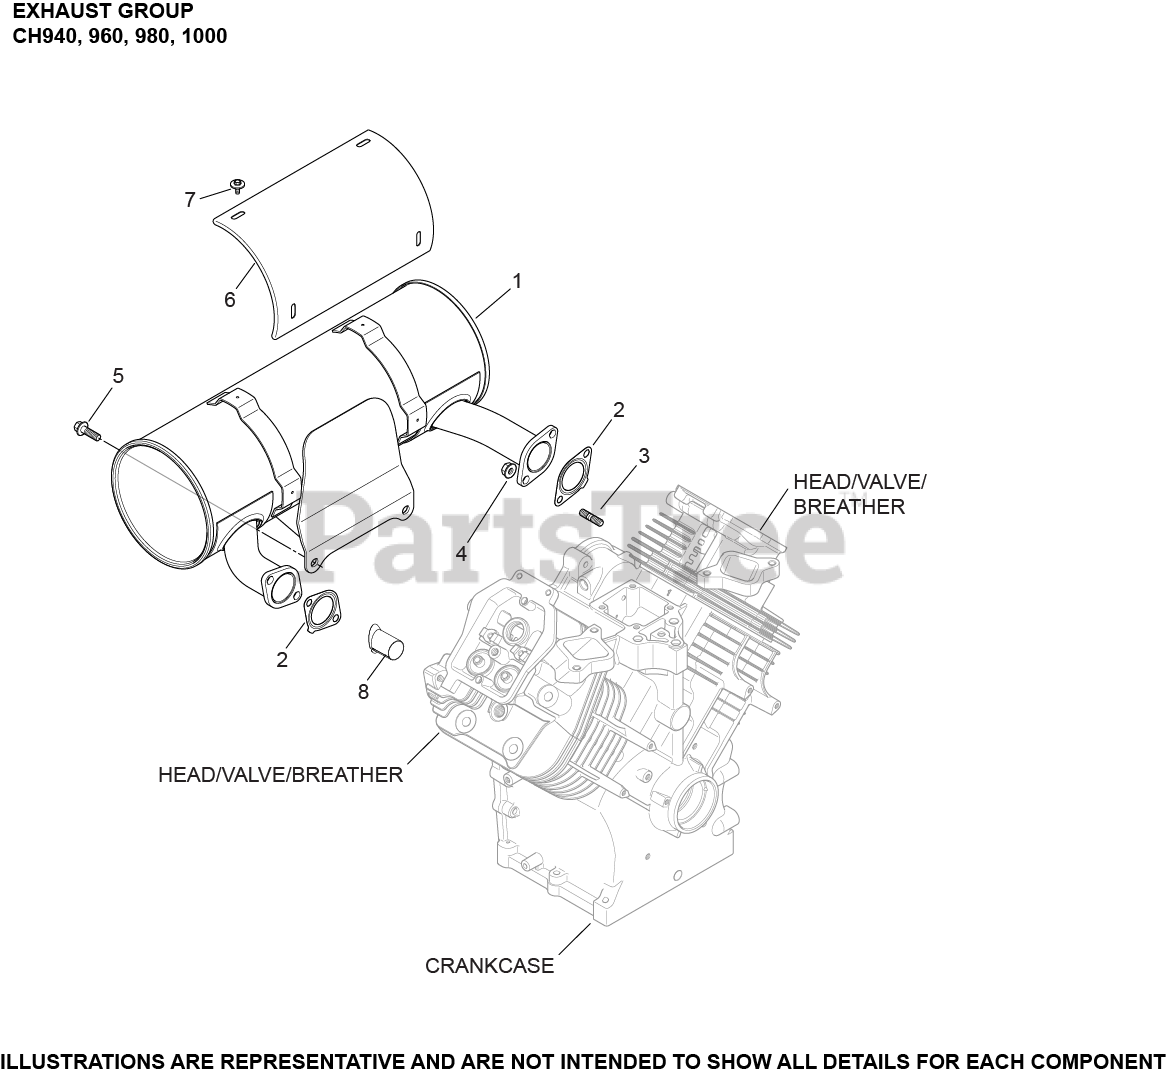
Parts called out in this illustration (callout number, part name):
1	KIT, MUFFLER STARTER SIDE
2	GASKET, EXHAUST
3	STUD, EXHAUST (KM)-USE 25 072 24-S
4	NUT, FLG M8X1.25
5	SCREW, FLG M8X1.25X25
6	SHIELD, HEAT
7	SCREW, SEMS DRILL #8-18X1/2"
8	LINER, EXHAUST PORT
